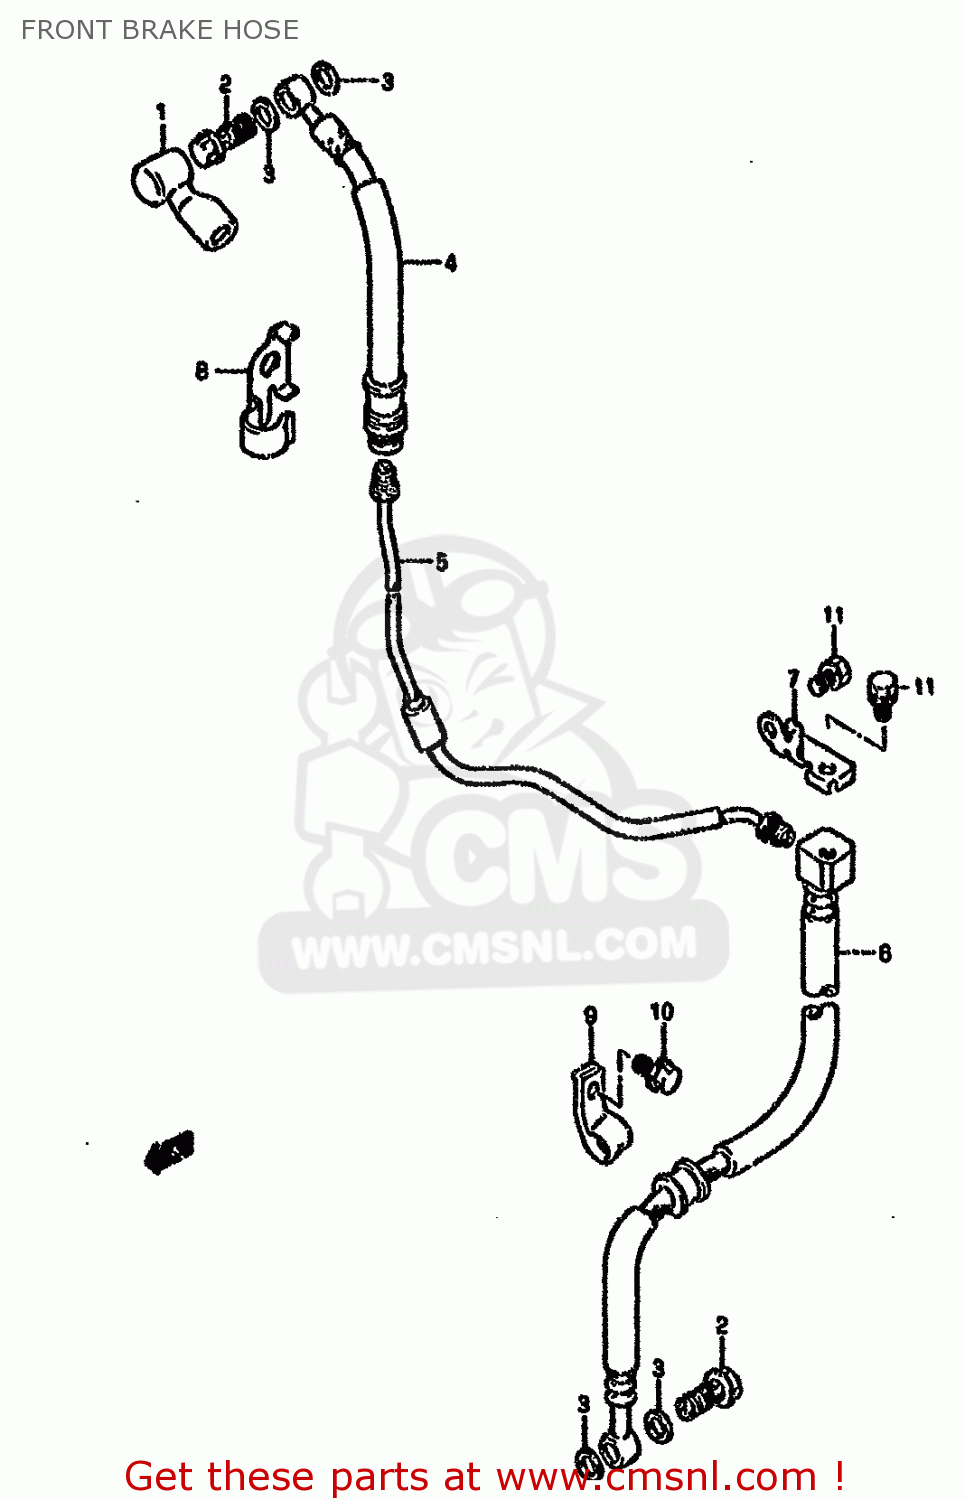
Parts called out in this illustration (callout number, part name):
1	BOOT,MASTER CYLINDER
2	BOLT UNION
3	WASHER(10X15X1.5)
4	HOSE,FR BRAKE NO.1
5	PIPE,FRONT BRAKE
6	HOSE,FR BRAKE NO.2
7	BRACKET,FRONT BRAKE HOSE
8	CLAMP,FR BRAKE HOSE NO.1
9	CLAMP,FR BRAKE HOSE NO.2
10	BOLT
11	BOLT
